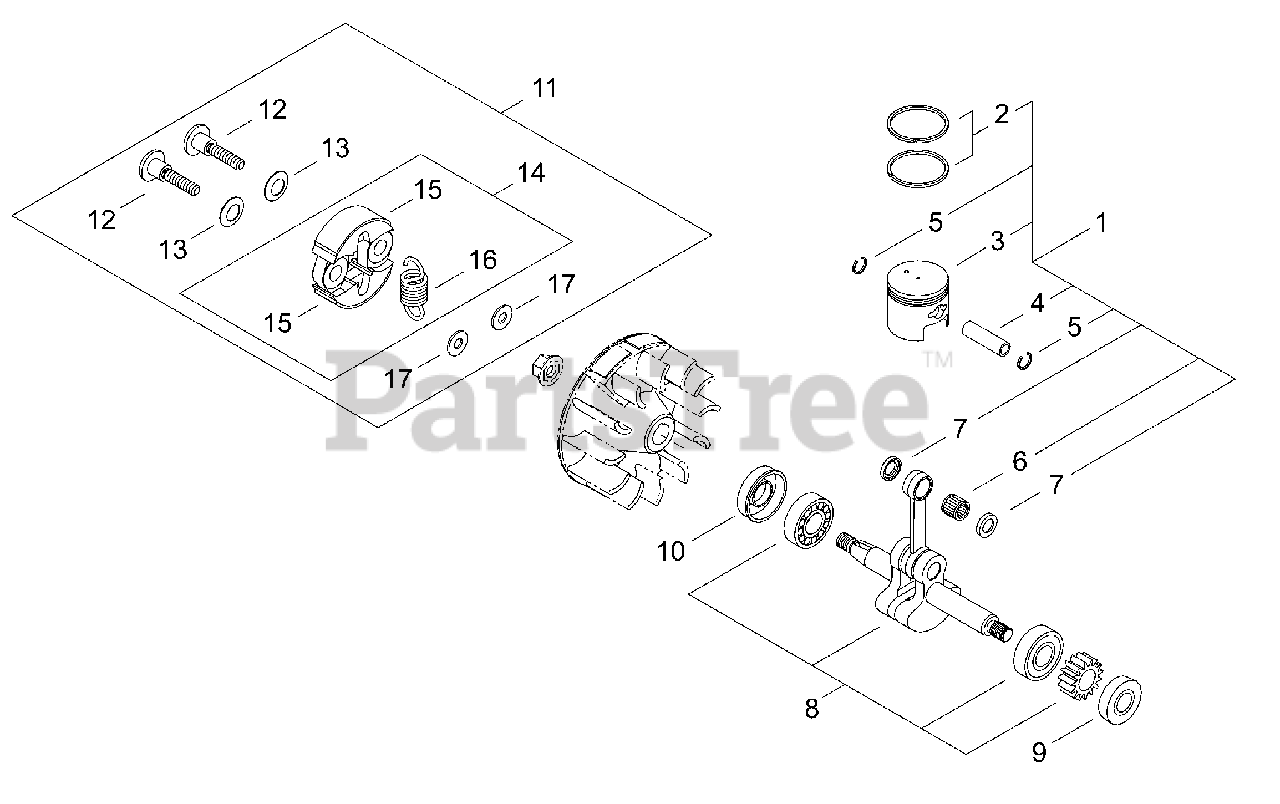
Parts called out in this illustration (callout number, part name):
1	PISTON KIT
2	RING, PISTON
3	PISTON
4	PIN, PISTON
5	RING, SNAP
6	BEARING, NEEDLE 9
7	WASHER, THRUST 9
8	CRANKSHAFT ASSY
9	SEAL, OIL 12
10	SEAL, OIL 12
11	CLUTCH ASSY
12	BOLT, CLUTCH
13	WASHER, SPRING
14	SHOE ASSY, CLUTCH
15	SHOE, CLUTCH
16	SPRING, CLUTCH
17	WASHER 6 MM
